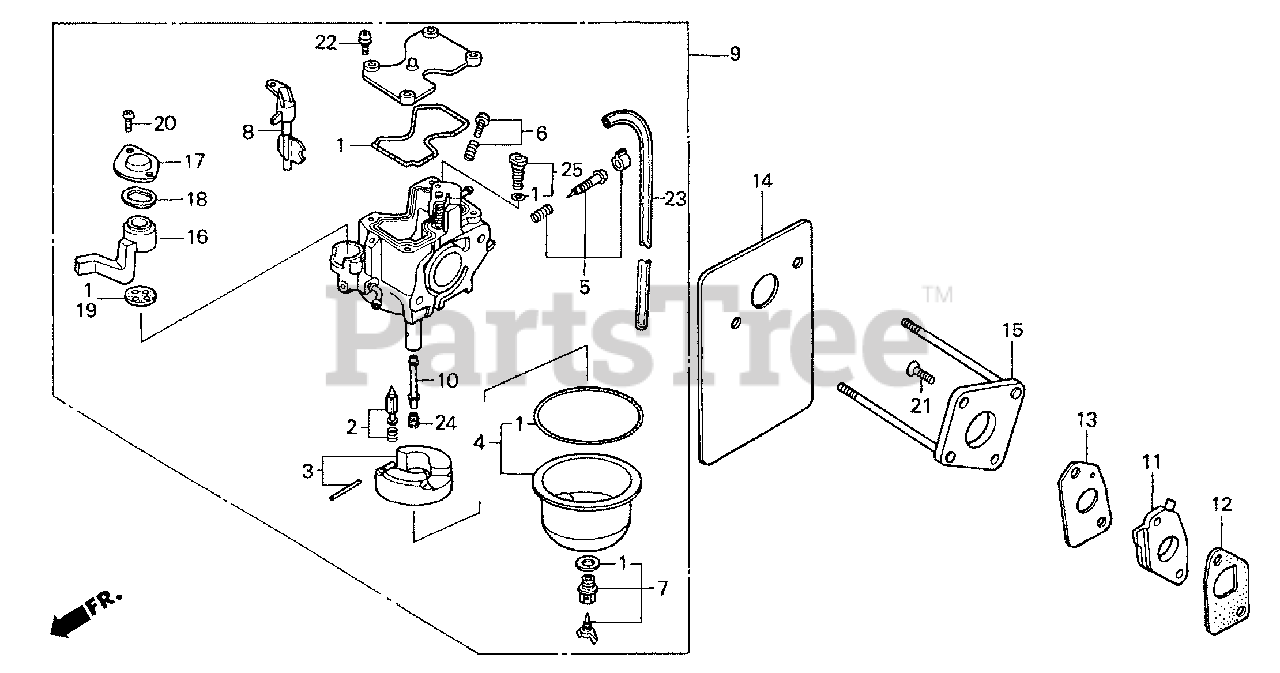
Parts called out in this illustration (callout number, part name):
1	GASKET SET
2	VALVE SET, FLOAT
4	CHAMBER SET, FLOAT
7	SCREW SET
8	LEVER SET, CHOKE
9	CARBURETOR ASSY. (BF22B D)
10	NOZZLE, MAIN
11	INSULATOR, CARBURETOR
12	GASKET, INSULATOR
13	GASKET, CARBURETOR
14	GASKET, CARBURETOR
15	PLATE, CARBURETOR JOINT
16	LEVER, VALVE
17	PLATE, LEVER SETTING
18	SPRING, VALVE LEVER
19	GASKET, VALVE
20	SCREW, PAN (3X6)
20	SCREW, PAN
21	SCREW, FLAT (5X20)
22	SCREW, PAN
23	BULK HOSE, VINYL (4.5X8X1000) (4.5X8X750)
24	JET, MAIN (#60) Use up to Engine SN BF22B C.
24	JET, MAIN (#62) Use up to Engine SN BF22B C.
24	JET, MAIN (#65)
24	JET, MAIN (#55) Use from Engine SN BF22B D.
24	JET, MAIN (#58) Use from Engine SN BF22B D.
24	JET, MAIN (#60)
25	JET SET, PILOT (#35)
